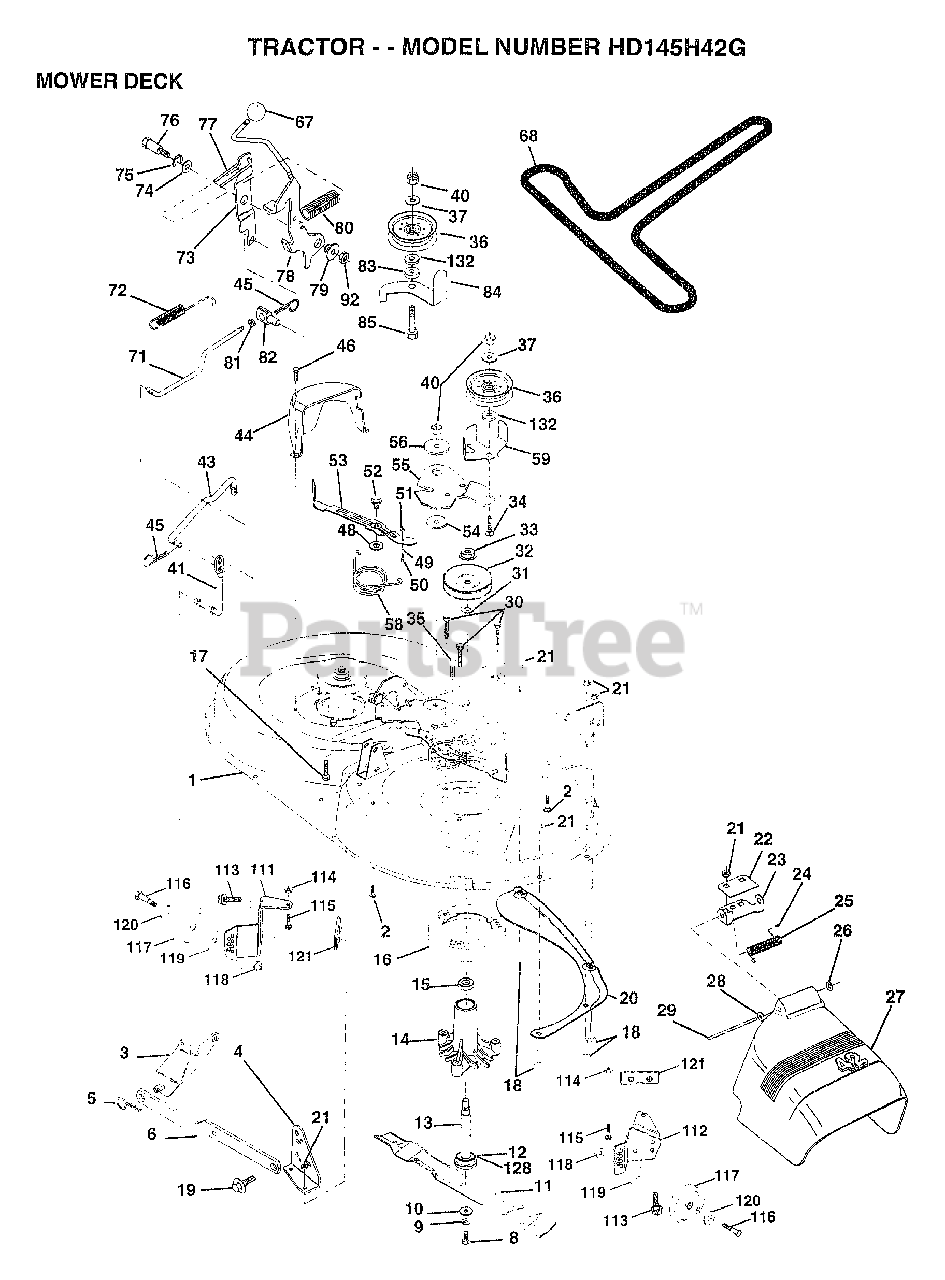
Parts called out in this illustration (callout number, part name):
1	DECK.WELD.42.
2	BOLT
3	BRKT ASM SWAY BAR
4	BRKT DECK SW BAR
8	BLADE BOLT
10	WASHER.HARD.BLADE
11	"BLADE.42"" HIPERF"
12	BEARING.BALL
14	HSG ASM MANDREL
15	BEARING
16	STRIPPER RND MWR
17	BOLT RDHD 3/8-16
18	BOLT
19	BOLT SHD 5/16-18
22	STIFFENER BRKT
23	DEFLECTOR BRKT
24	CAP-SLEEVE LT
25	SPRING TORSION
26	NUT PUSH M
27	DEFLECTOR.SHIELD
28	WASHER
29	HINGE ROD
30	SCREW THDROL WASHER HEAD
31	WASHER
32	PULLEY.MANDREL.42
34	BOLT
35	XMAS TREE FASTNER
36	FLAT IDLER PULLEY
37	WASHER
41	PIVOT ROD
43	ROD CLUTCH W/NIBS
44	GUARD MAND LH BLK
45	RETAINER M
46	SCREW.1/4-20X5/8
48	HARD SMALL WASHER
49	ROLLER ASM-CAM
50	SHOULDER BOLT
51	LOCKNUT
52	BOLT.SHLD.5/16-18
54	HARDENED WASHER
55	ARM-IDLER
56	SPACER RETAINER
58	SPRING TORSN BRAK
59	GUARD IDLER TUV
67	KNOB T(3/8 HOLE)
68	BELT.V.T-PATH
71	ROD CLUTCH 38/42
72	RETURN SPRING
73	CLUTCH ARM SECOND
74	WASHER
75	RING
76	SHOULDER BOLT
77	SPRING KEEPER
78	LEVER ASM-CLUTCH
79	BUSHING
80	SPRING.CLUTCH.MWR
81	NUT
82	TRUNION ADJ
83	WASHER
84	"KEEPER-BELT,FIXED"
85	BOLT RDHD 3/8-16
92	NUT
111	BRACKET.GWHL.LH.
112	BRACKET.GWHL.RH.
113	SCREW
116	BOLT M
117	WHEEL.GAGE.BLK.PL
118	LOCKNUT
119	WASHER
120	WASHER
121	BRACKET.EXTRD.GWL
128	WASHER.FELT.
132	WASHER GT
